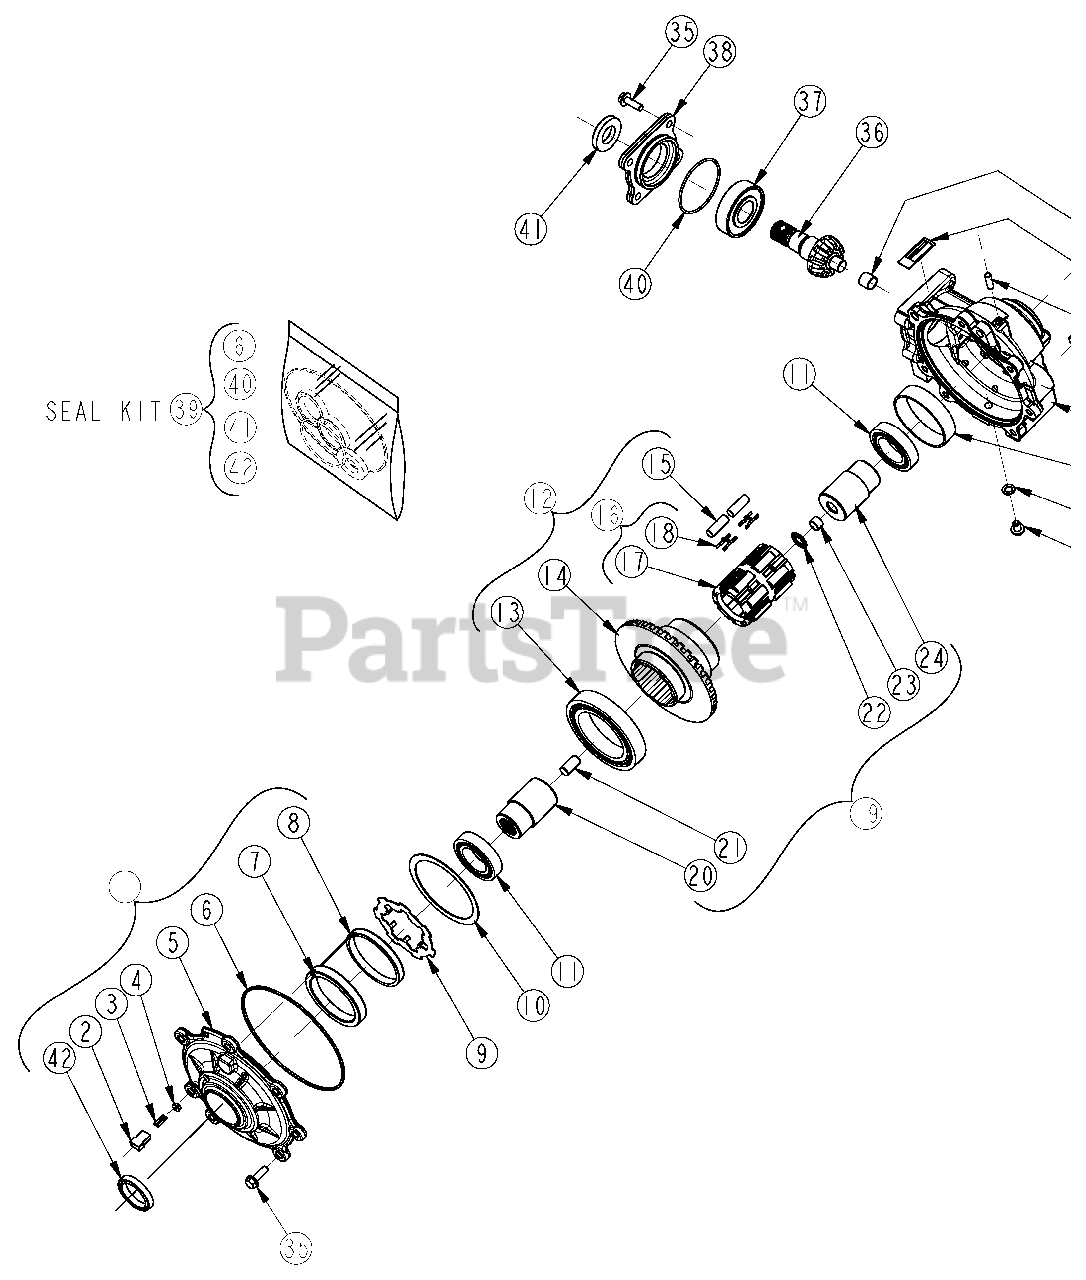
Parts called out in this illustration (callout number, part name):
9	ARMATURE PLATE
10	SHIM .05 THICK BRASS, HALF HARD
11	6008-C3 DEEP GROOVE ROLLER BEARING 4£
12	CLUTCH ASSEMBLY #12 Kit includes #13 to #16
13	6015-C3 DEEP GROVE ROLLER BALL BEARING Sold separately & with #12 kit
14	CLTH.HSG./RNG GR., 42T 6.75DP Sold separately & with #12 kit
15	ROLL KIT Sold separately & with #12 kit
16	ROLL CAGE ASSEMBLY #16 Kit includes #17 & #18
18	SPRING KIT, H-CLIP .008 THK Sold separately & with #16 kit
19	RACE/OUTPUT HUB ASSEMBLY #19 Kit includes #20 to #21
21	PERMIGLIDE BUSHING Sold with #19 kit
22	TC815 NEEDLE ROLLER THRUST BEARING Sold separately & with #19 kit
23	1/2 DIA X 1 LG. DOWEL PIN Sold separately & with #19 kit
25	GEARCASE ASSEMBLY #25 Kit includes #26 to #32
26	DU BUSHING Sold with #25 kit
29	PLUG OIL FILL 3/4-16 HOLLOW HEAD Sold separately & with #25 kit Torque item #29 (PLUG
32	DRAIN PLUG ASSEMBLY #32 Kit includes #33 & #34
35	BOLT KIT Torque item #35 (5/16" x 1" Hex Head Bolts) Tighten to17 ft-bs
36	SHAFT PNION 11T3.75DP, MACHINED
37	6306-03-C3 DP GROOVE ROLLER BALL BEARING
38	COVER PLATE, INPUT-MACHINED
39	MINOR REPAIR KIT #39 Kit includes #6 & #40 to #42
41	TRIPLE LIP OIL SEAL Sold with #1 kit & #39 kit
42	OIL SEAL, OUTPUT Sold with #39 kit
